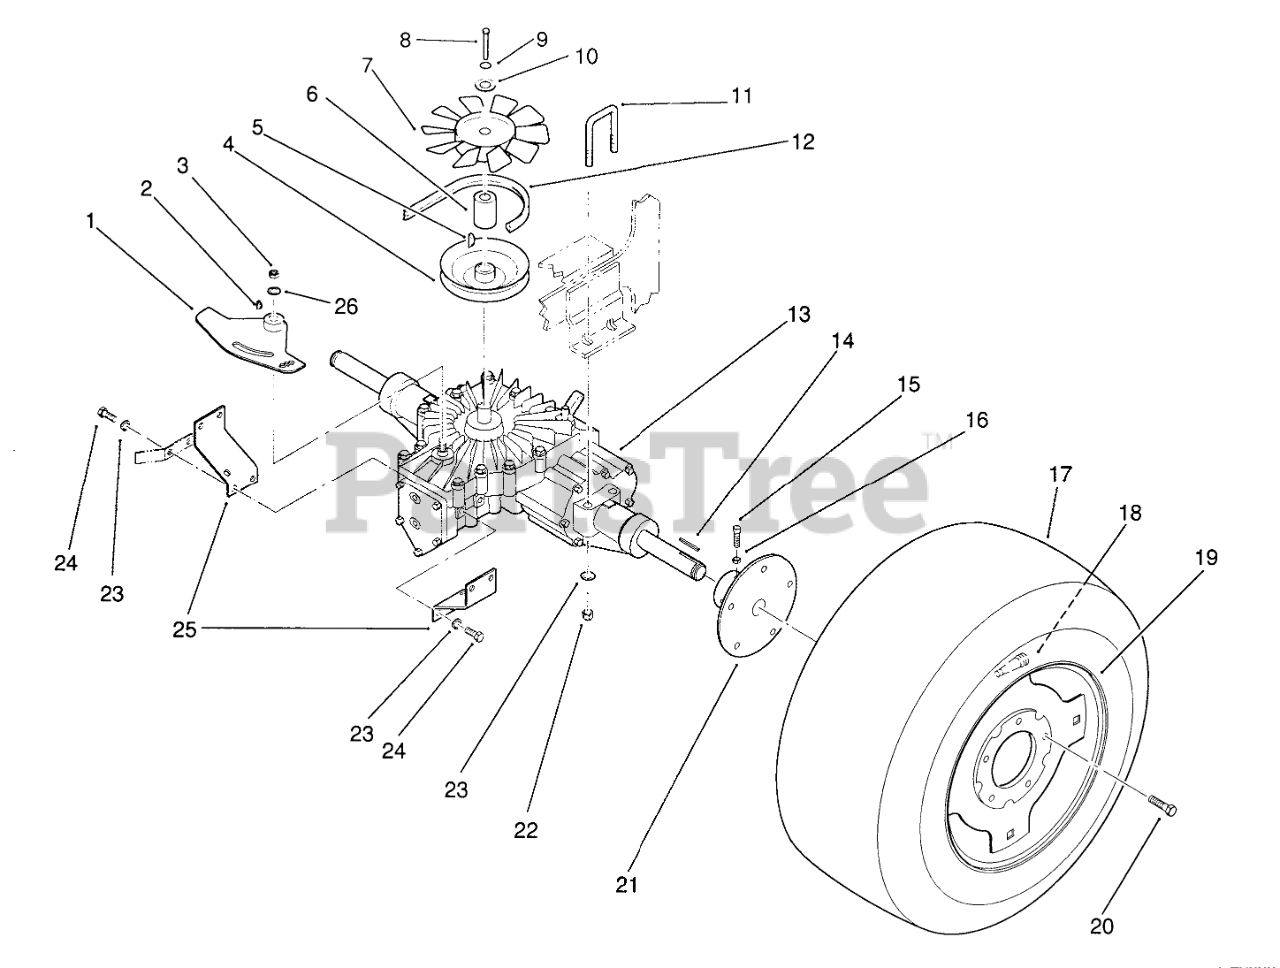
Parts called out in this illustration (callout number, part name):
1	WLDMT-CONTROL ARM
2	KEY WOODR 1/8X1/2 DI
3	Nut
4	PULLEY-TRANS
5	HARD HI PRO KEY
6	SPACER
7	FAN-7"
8	Screw
9	Washer
10	WASHER
11	U-BOLT
12	BELT-V
13	Trans.-Eaton 750-034
14	Key
15	Screw-Set
16	Nut
17	TIRE
18	VALVE
19	WHEEL
20	Lug Nut
21	Hub-Rear
22	NUT
23	Washer
24	HHCS
25	BRACKET R
26	Washer
